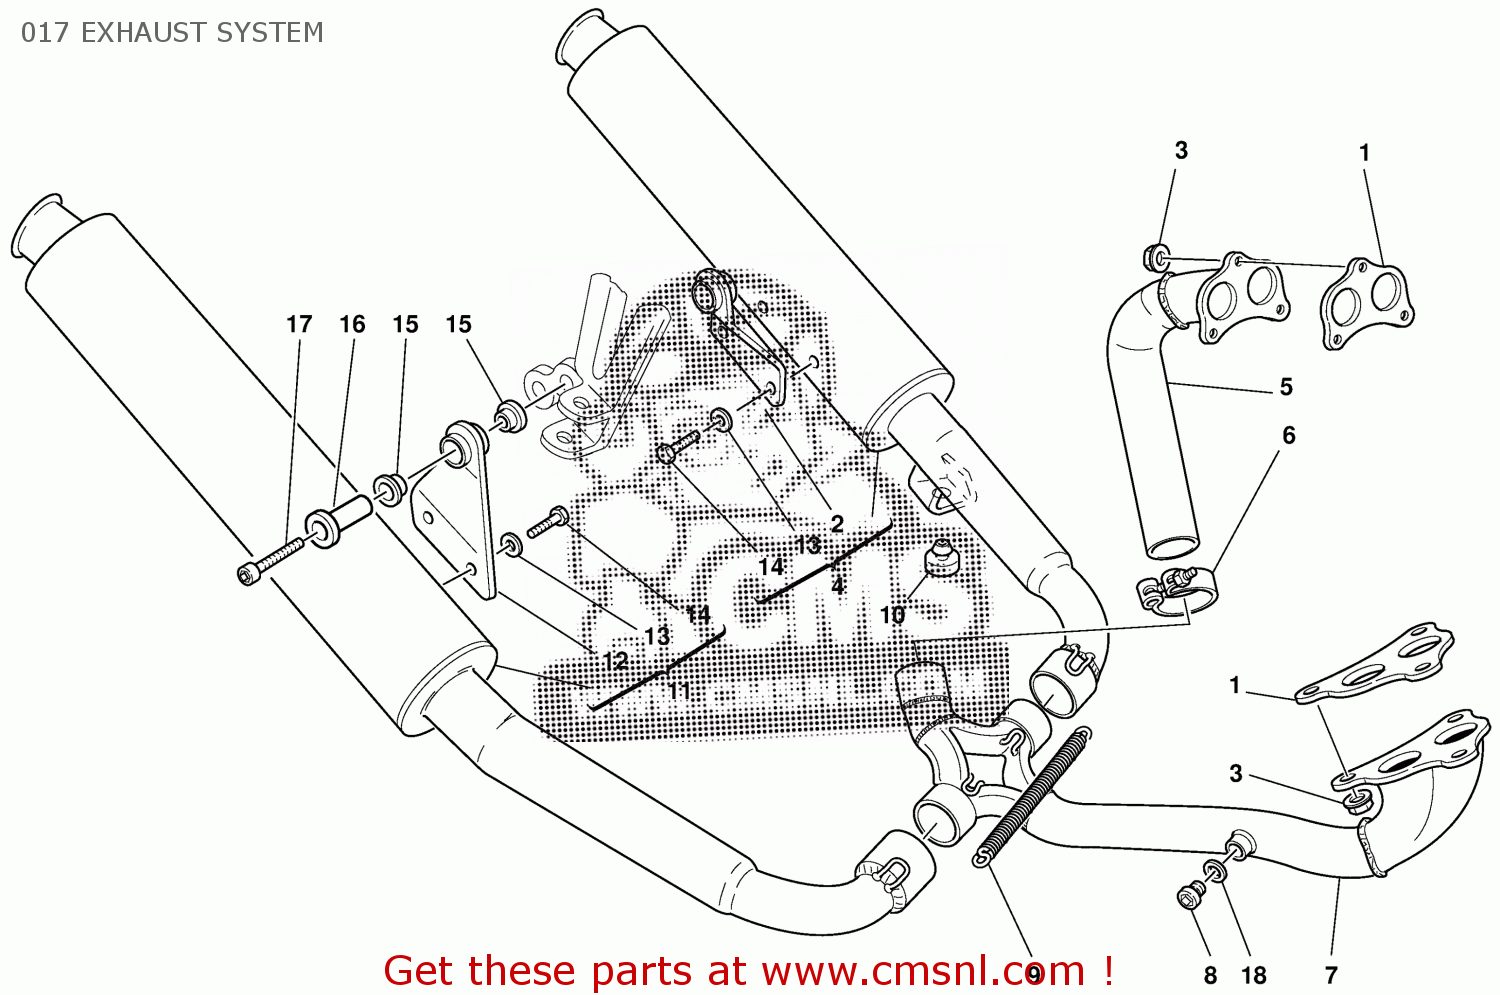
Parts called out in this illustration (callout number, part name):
1	GASKET, EXHAUST PIPE
2	LEFT BRACKET
3	NUT
4	LEFT SILENCER
5	VERTICAL EXHAUST PIPE
6	CLAMP
7	HORIZONTAL EXHAUST PIPE
8	PLUG ASSY
9	SPRING
10	RUBBER PAD
11	RIGHT SILENCER
12	RIGHT BRACKET
13	WASHER
14	SCREW
15	DAMPER
16	COLUMN
17	SCREW M8X35
18	COPPER GASKET 11.9X8.2X2
